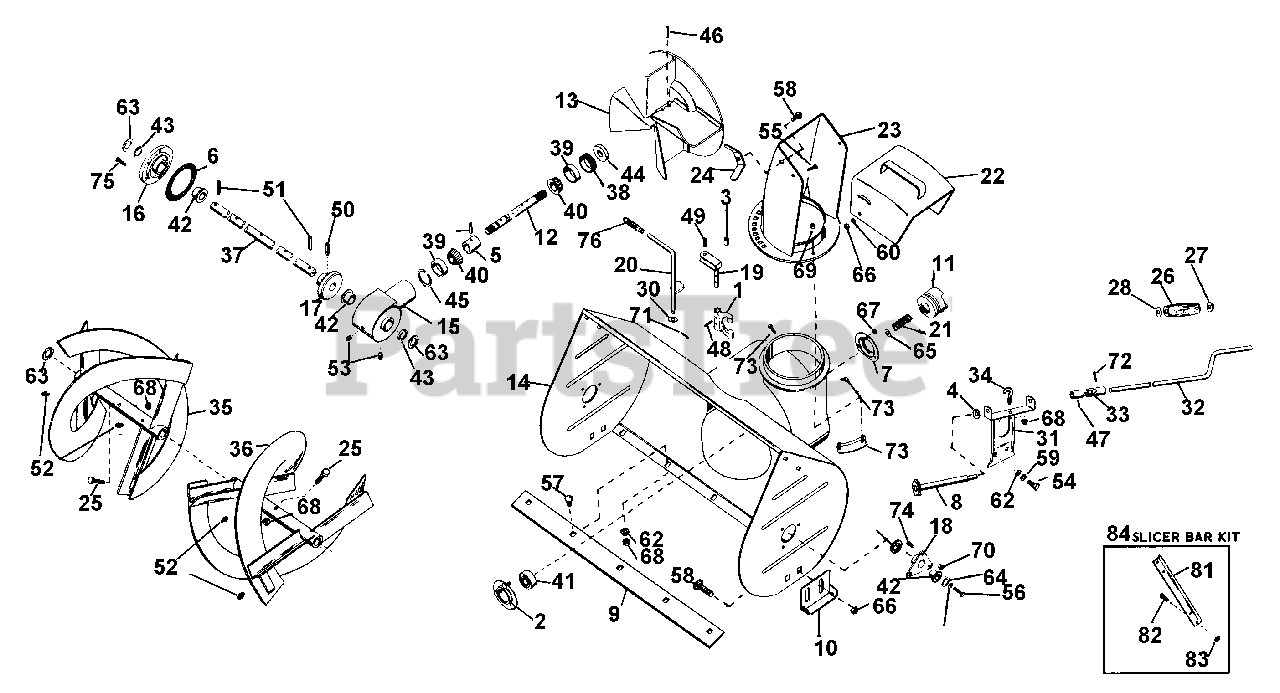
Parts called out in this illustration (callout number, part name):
1	CLUTCH FORK
2	BEARING FLANGE
4	WAVE WASHER .531X.781X.125FH
5	BEARING SPACER
7	BEARING FLANGE
8	CONTROL SPROCKET
9	SCRAPER BLADE 24"
10	RUNNER
11	JAW CLUTCH
12	HELICON PINION SHAFT
14	BLOWER HOUSING
15	CASE, GEAR - C.I.
16	GEAR CASE FLANGE
17	HELICON GEAR - 41 TOOTH
18	BEARING SUPPORT
19	FORK SHAFT
20	FORK CAM
21	SPRING
22	DEFLECTOR CHUTE
23	DISCHARGE CHUTE
24	WING NUT
25	SHEAR BOLT YWZC
27	CAP, 3/8 ROD YWZC
28	FASTENER
29	WAVE WASHER .406X.750X.063FH
30	CHUTE CLAMP
31	CHUTE CNTL BRACKET
32	CHUTE CNTL CRANK
33	UNIVERSAL JOINT
35	R H RAKE
36	L H RAKE
37	FRONT GEAR SHAFT
38	ADJUSTMENT PLUG
39	BRG-CUP 1.781X.475
40	BRG-CONE .750X.61
41	BRG-BALL .750X1.750X.50
42	BSHG-FLG 1.000X1.12X.62X1.50BR
43	SEAL 1.000X1.312X.150
44	SEAL .750X1.499X.225
45	RG-RTNG INT 1.781 HSG X.062
46	PIN-ROLL .250X1.25
47	PIN-ROLL .125X1.00
48	PIN-ROLL .250X1.25
49	PIN-ROLL .250X1.25
50	PIN-ROLL .313X1.38
51	PIN-ROLL .188X1.25
52	HYDRAULIC DRIVE FITTING
53	PIPE PLUG
54	BLT-HEX .31-18X.63 PL GR 2
55	BLT-HEX .31-18X.63 PL GR 2
56	BLT-HEX .31-18X.63 PL GR 2
57	BLT-RDHDSQSHNK .31-18X.50 YZ
58	BLT-RDHDSQNK .38-16X.75 SHT PL
59	WSHR-LK .312X.097 PL HVY
60	WSHR-LK .375X.115 HVY PL
61	WSHR-LK .500X.151 HVY PL
62	WSHR-FL-STL .38X.875X.083 PL
63	BRG-CUP 2.328X.465
64	BRG-CONE 1.25X.66
65	BRG-CUP 3.346X.532
66	NUT-LK-CTR .375-16 GR A PL
67	NUT-LK-CTR .250-20 PL
68	NUT-LK .312-18 GR A PL
69	NUT-KEPS 10-24 PL
70	NUT-LK-FLG .250-20 PL
71	PIN-COTR .12X1.0 PL
72	PIN-COTR .09X.75 PL
73	BLT-SCRHFWH .38-16X.50 PL
74	SCR-SLTR-SERNK .25-20X.62 PL
75	BLT-SERHFWH .25-20X.75 PL
77	DISCHARGE CAUTION LABEL
78	DISCHARGE CAUTION LABEL
79	MOWER IN-OUT LABEL
80	MOWER IN-OUT LABEL
81	CUTTER BAR
82	BLT-RDHDSQSHNK .31-18X.50 YZ
83	NUT-LK .312-18 GR A PL
84	Slicer Bar Kit(Inc. 81,82,83)
